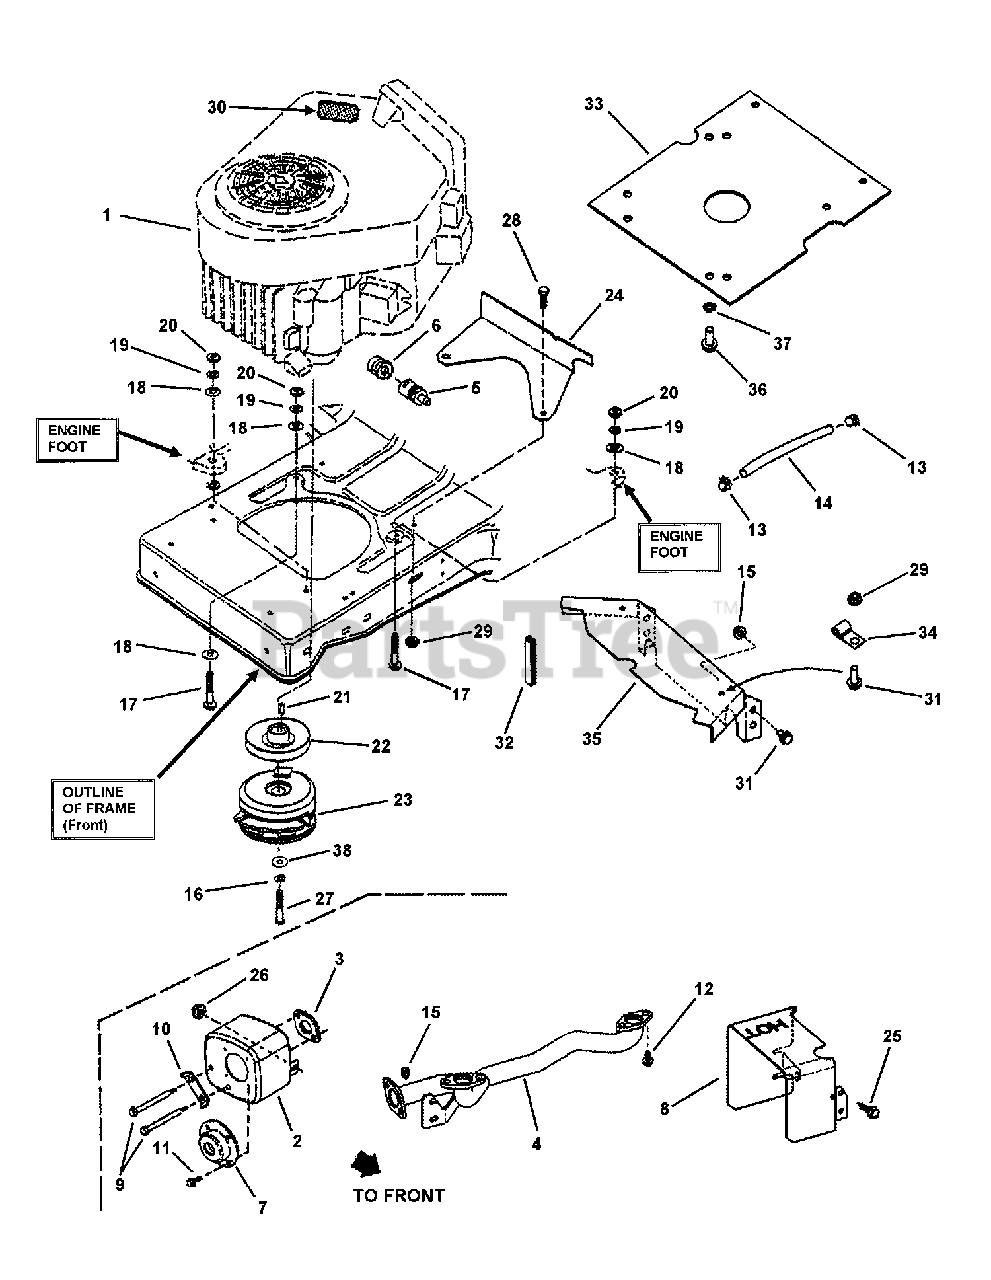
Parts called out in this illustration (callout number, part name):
2	MUFFLER, 16HP B&S
3	GASKET, Muffler/Exhaust
3	GASKET, Muffler/Exhaust, 20 HP Intec
4	WELDMENT, Manifold 16HP
5	ASSEMBLY, Oil Valve
6	EXTENSION, Oil Drain
7	DEFLECTOR, Exhaust (Direct Out)
8	SHIELD, Muffler/Heat
9	SHOULDER BOLT, 5/16-18 thread x 4"
10	SCREW LOCK
11	SCREW, #8-18 x 1/2" Hex Head Sheet Metal
12	SCREW, 5/16-18 x 1/2" Hex Washer Self-Tap
13	CLAMP, .490 x .31
14	FUEL LINE, 10" long
14	FUEL LINE, 3-3/4" long
15	NUT, 5/16-18 Hex Flange Lock, GR 5
16	WASHER, 7/16" Split Lock
17	SCREW, 5/16-18 x 1-3/4" Hex Head Cap, GR 5
18	WASHER, 5/16" Flat
19	WASHER, 5/16" Split Lock
20	NUT, 5/16-18 Hex, GR 5 or B
21	KEY, 1/4 Square x 1-3/4"
22	PULLEY, Traction Drive 42&48 TT K46
23	ELECTRIC CLUTCH, Ogura MA-GT-DX11CU
24	SHIELD, Muffler/Heat, B&S 16HP
25	SCREW, 1/4-20 x 5/8" Hex Head Cap, GR 5
26	NUT, 1/4-20 Hex Flange Lock
27	SCREW, 7/16-20 x 2-1/2" (Special), GR 5
28	SCREW, 5/16-18 x 1" Hex Head Cap, GR 2
29	NUT, 5/16-18 Hex Flange Lock, GR 5
30	DECAL, Warning-Speed Setting 14, 16, & 18 HP ENGINES
31	BOLT, 5/16-18 x 5/8" Hex Flange Lock
32	TRIM, Heat Shield (2" long)
32	TRIM-Heat Shield (3" long)
33	PLATE, Engine- Briggs Engine
34	CLIP, "J" Open Type .4 Bundle Dia., .281 Dia. Hole
35	HEAT SHIELD, B&S V-Twin Engine
36	SCREW, 3/8-16 x 1" Hex Washer Self-Tap
37	WASHER, 5/16" Split Lock
38	WASHER, 7/16" I.D. x 1-1/2" O.D. x .188 thick
